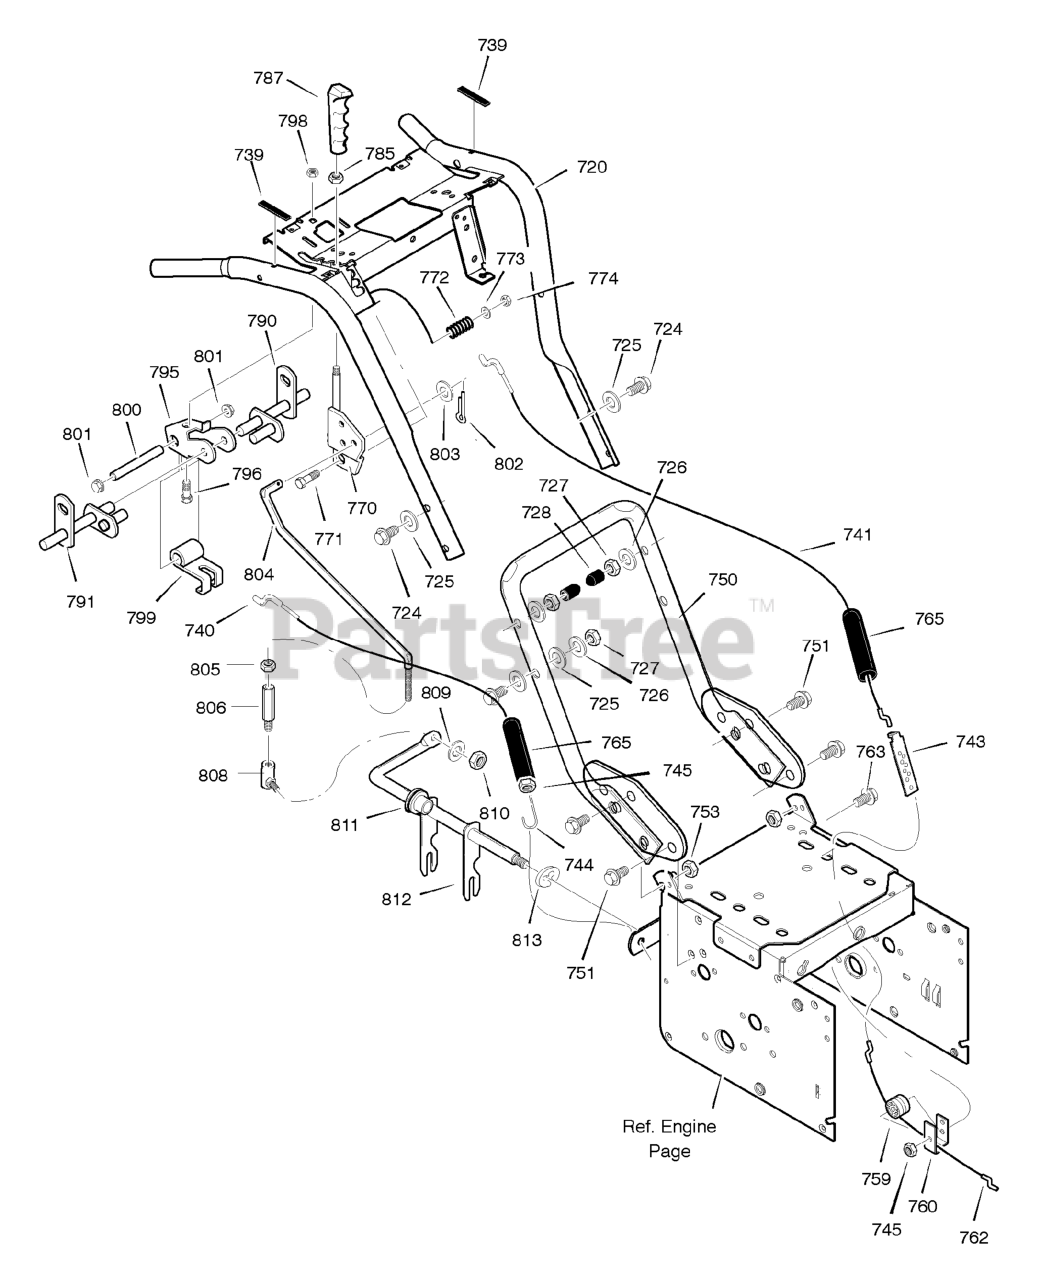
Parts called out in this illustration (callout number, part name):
720	ASSY, HANDLE
724	SCREW
725	WASHER, FLAT
726	WASHER
728	STOP, PLASTIC
739	BUMPER
740	CABLE, AUGER CLUTCH
741	CABLE, DRIVE
743	BRKT, CABLE ADJ
744	SPRING, CLUTCH
745	NUT, HEX
750	HANDLE, LOWER
751	SCREW
753	NUT, 5/16-18
759	SPOOL, CABLE
760	BRKT, SPOOL
762	CABLE, LOWER DRIVE
763	BOLT, HEX 1/4-20 x 1.5
765	BOOT, CABLE
770	BRACKET, SHIFT
771	SCREW
773	WASHER, FLAT
774	NUT, HEX
785	NUT, HEX
787	KNOB, SHIFT
790	ROD, ASSY LH
791	ROD, ASSY RH
795	BRACKET, CAM
796	SCREW
798	NUT, NYLOCK
799	CAM LOCK
800	PIN, SPRING PIVOT
801	NUT, PUSH ON
802	PIN, COTTER
803	FLATWASHER
804	ROD, SPEED CONTROL
805	NUT, 5/16-18
806	ADAPTER, ROD
808	BALLJOINT, STEEL
809	WASHER
810	NUT, 5/16-18
811	BEARING, FL
812	ROD, YOKE
813	RETAINER, RING
